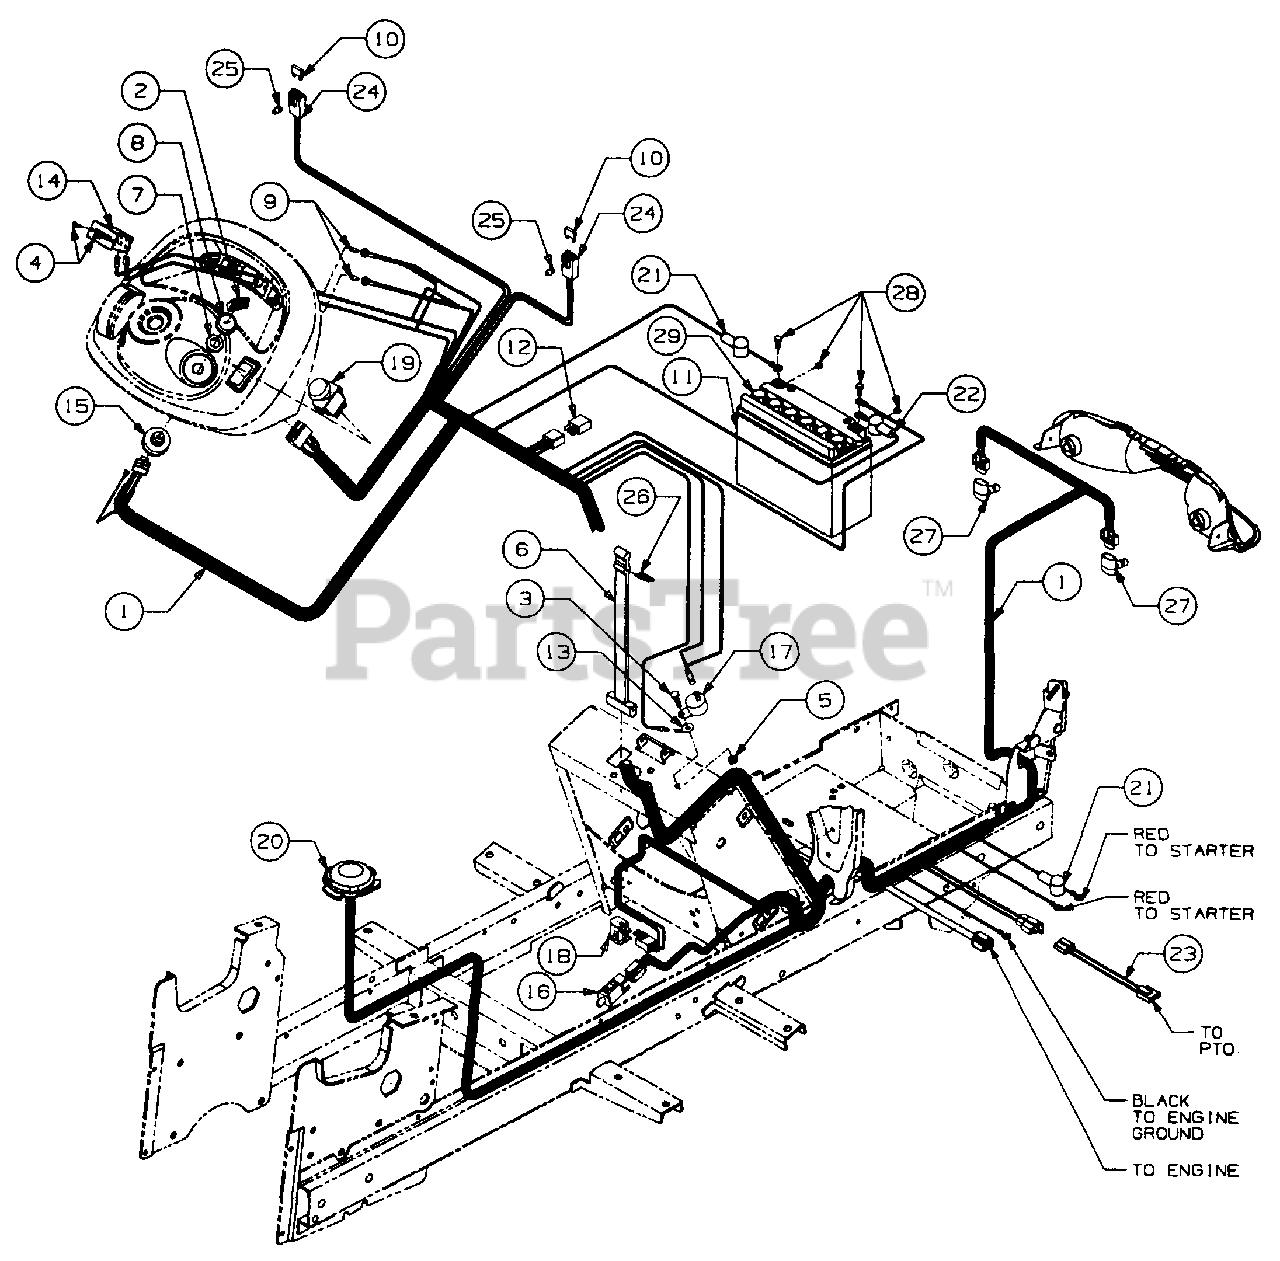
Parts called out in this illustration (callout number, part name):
1	Main Harness
2	Key, Ignition
3	Screw, Hex Cap, 1/4-20 x 1.0 Lg
4	Screw, Truss Hd Tapp, #6 x .62 Lg
5	Nut, Hex Sems, 1/4-20
6	Strap, Battery Retainer
7	Nut, Ignition Switch
8	Cap, Ignition Switch
9	Bulb, Indicator
10	Fuse, 25 Amp
11	Battery
12	Relay
13	Lug, Quick Connect
14	Hour Meter
15	Switch, Ignition
16	Switch, Interlock (Brake)
17	Indicator, Voltage
18	Switch, Snap Mount - Normally Closed (Reverse)
19	Switch, PTO
20	Switch, Seat
21	Cover, Terminal Red
22	Cover, Terminal Black
23	Adapter, PTO Harness
24	Holder, Fuse
25	Clip, Fuse Holder Mtg
26	Hook, Wire Rectangular
27	Bulb, Head Lamp
28	Bolt, Battery
29	Cap, Battery
